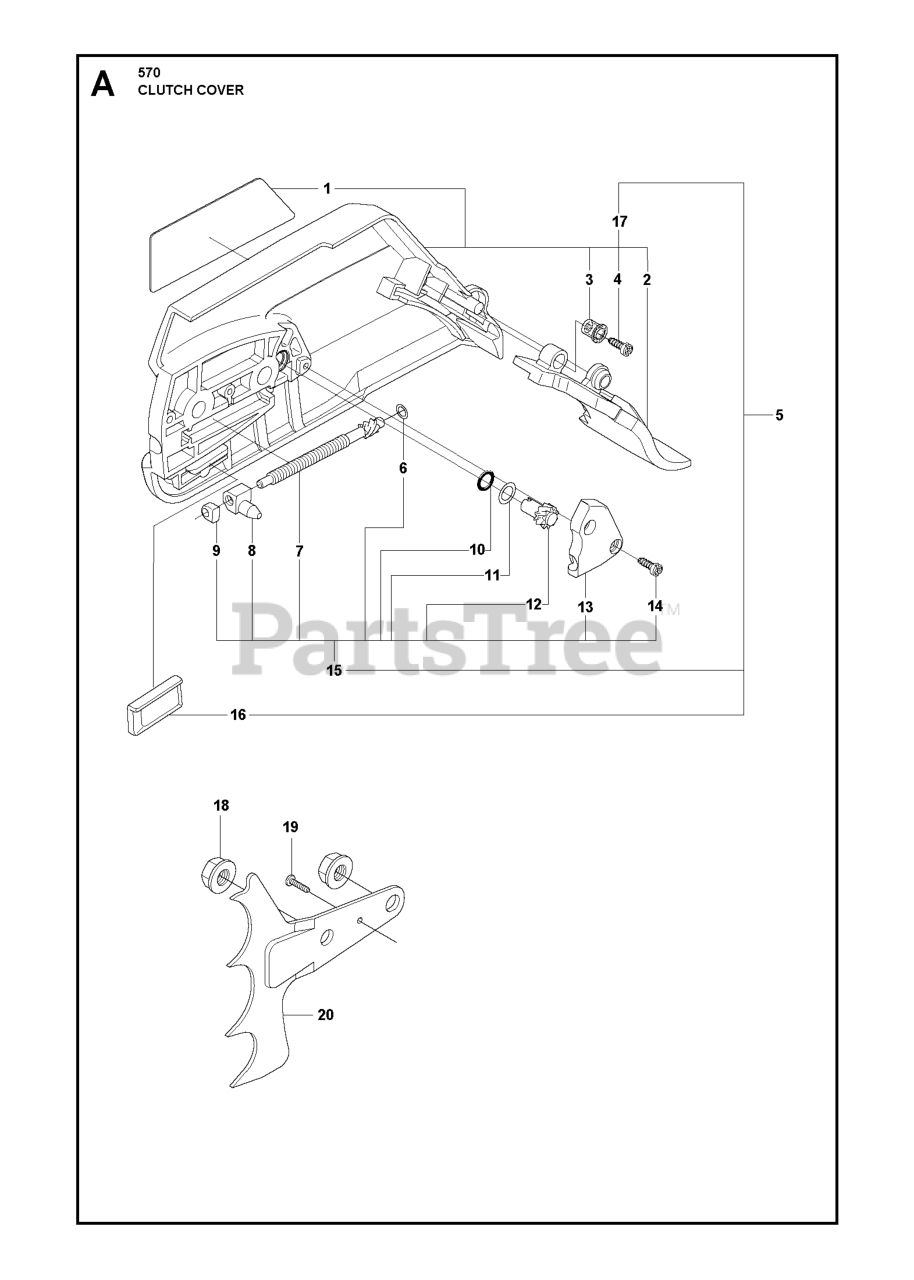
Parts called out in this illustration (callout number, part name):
5	CHAIN BRAKE COVER
7	ADJUSTER
12	RP ADJUSTER
15	KIT-CHAIN TENSIONER
16	CHAIN GUIDE
17	CHAIN BRAKE COVER
18	NUT M8 FLANGE
20	SPIKE OUTER
